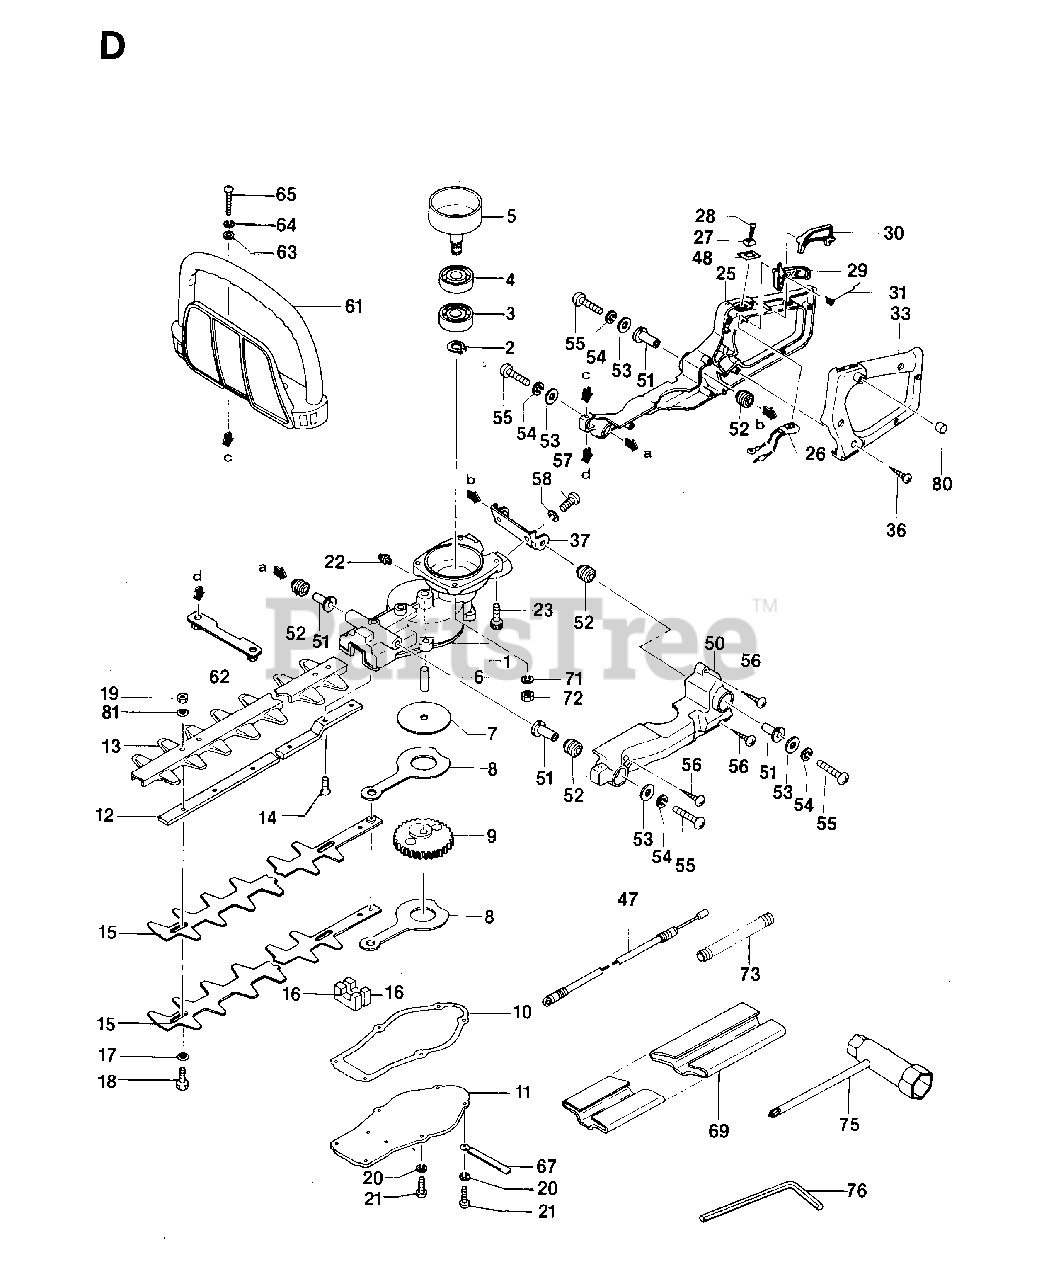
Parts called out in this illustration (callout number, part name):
2	RETAINING RING SGA 15
19	NUT
20	SPRING WASHER 4.1X7.1
54	SPRING WASHER
55	SCREW MC6S 5X30
57	SCREW MC6S 5X12
58	SPRING WASHER
63	WASHER 5.3X12
64	SPRING WASHER
65	SCREW MC6S 5X40
71	SPRING WASHER
72	NUT M6M M6
81	SPRING WASHER 6.4X11
